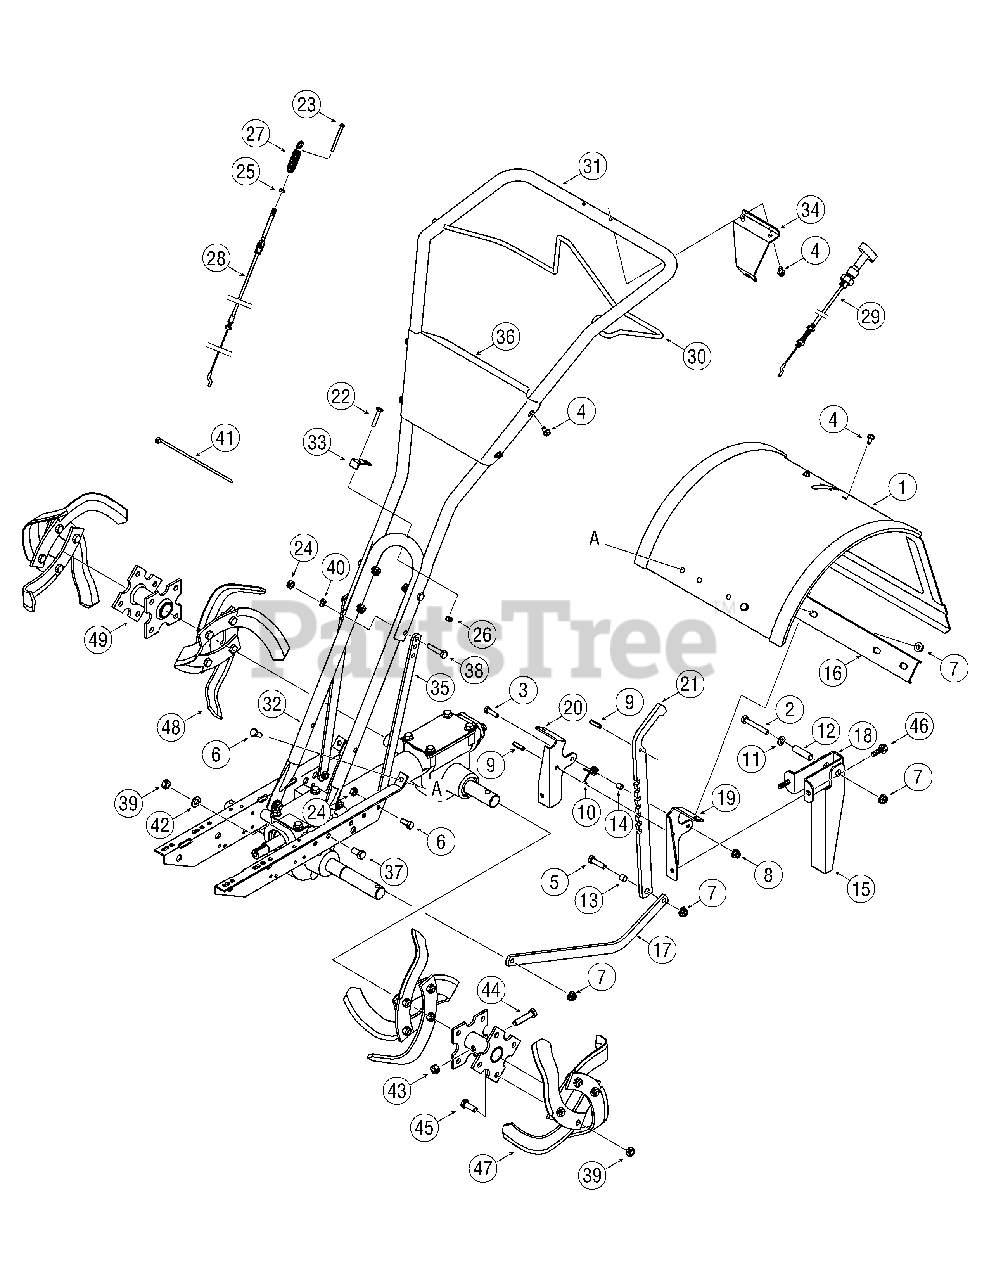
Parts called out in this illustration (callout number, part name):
1	Tine Hood Assembly (for model 643C)
1	Tine Hood Assembly (for models 643B & 645A)
2	Hex Screw, 5/16-18 x 2.25
3	Hex Hd. Screw, 1/4-20 x 1
4	Screw, Self-Tapping,1/4-20 x 1/2
5	Hex Hd. Screw, 5/16-18 x 1-1/4
6	Hex Hd. Screw, 5/16-18 x .75
7	Hex Lock Nut, Nylon, 5/16-18
8	Hex Lock Nut, Nylon, 1/4-20
9	Spirol Pin
10	Spring, Depth Regulator
11	Flat Washer, 5/16
12	Spacer, .462 x .328 x 1.63
13	Bushing
22	Hex Hd. Screw, 1/4-20 x 1-1/4
23	Screw, #10-24 x 2
24	Hex Lock Nut, 5/16-18
25	Hex Nut, #10-24
26	Hex Lock Nut, 1/4-20
27	Spring, Forward Clutch
28	Cable Assembly, Forward Clutch
29	Cable Assembly, Reverse Clutch (for models 643B & 645A)
30	Bail, Forward Clutch
37	Screw, Hex, 3/8-16 x 3/4
38	Screw, Hex, 5/16-18 x 1-1/2
39	Hex Lock Nut, 3/8-16
40	Lock Washer, 5/16
41	Cable Tie
42	Flat Washer, 3/8
43	Flange Lock Nut 3/8-16
44	Hex Hd. Screw, 3/8-16 x 1-3/4
45	Hex Hd. Screw, 3/8-16 x 1, Grade 5
46	Flange Screw .312-18 x 1.00
